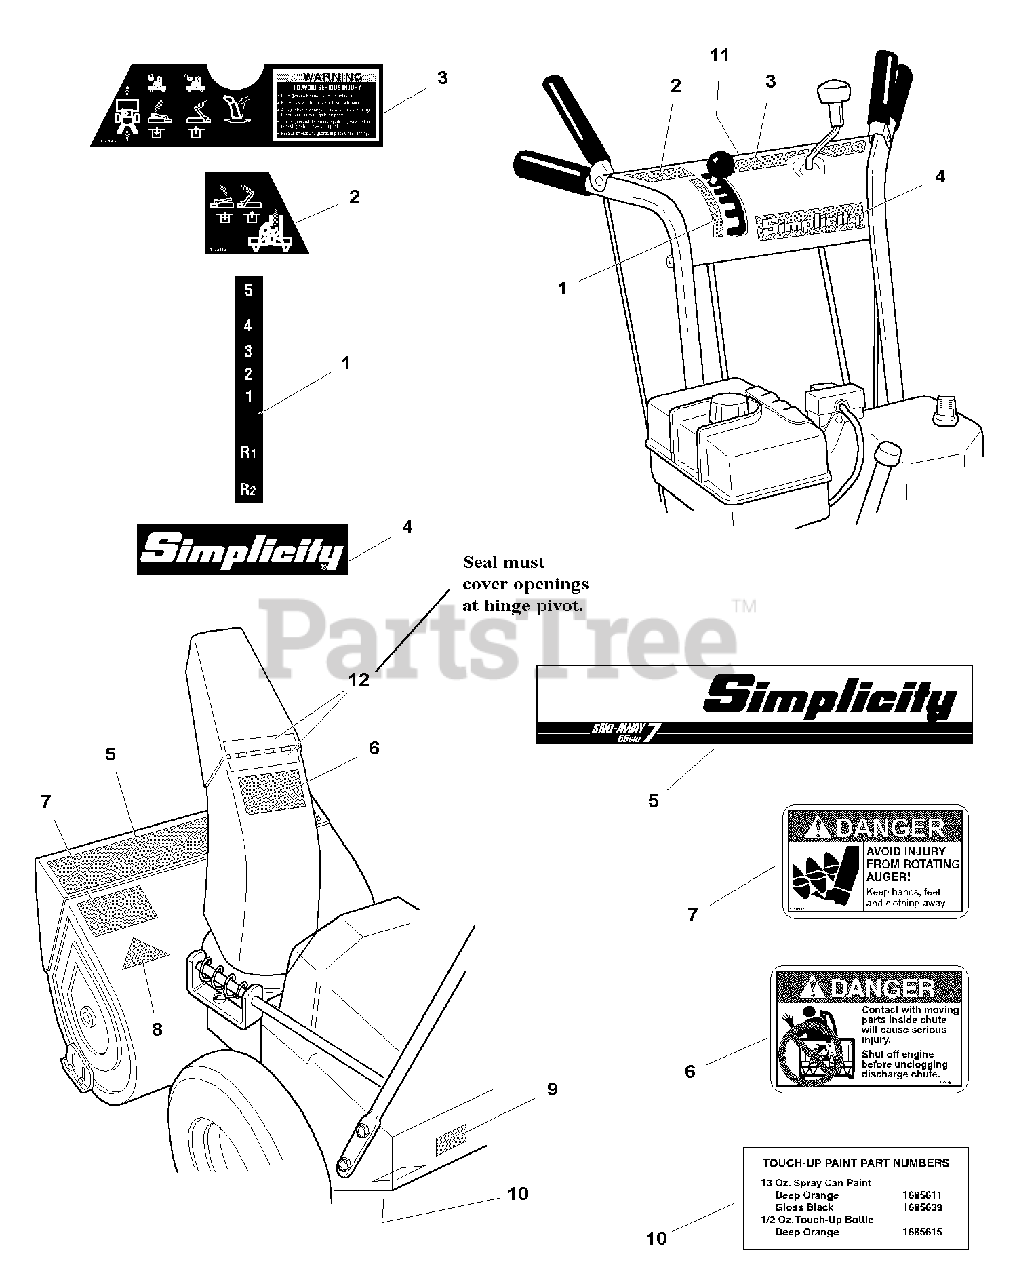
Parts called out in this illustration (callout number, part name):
1	DECAL, Speed Selector
2	DECAL, Auger Control
3	DECAL, Warning / Main Dash Panel
4	DECAL, Simplicity Logo
6	DECAL, Danger, Discharge Chute
7	DECAL, Danger, Auger
8	DECAL, OPEI (Not Serviced)
9	I.D. Tag (Not serviced)
10	DECAL, Touch-up Paint ID
11	DECAL, Handle Lubrication
12	DECAL, Hinge, Orange
